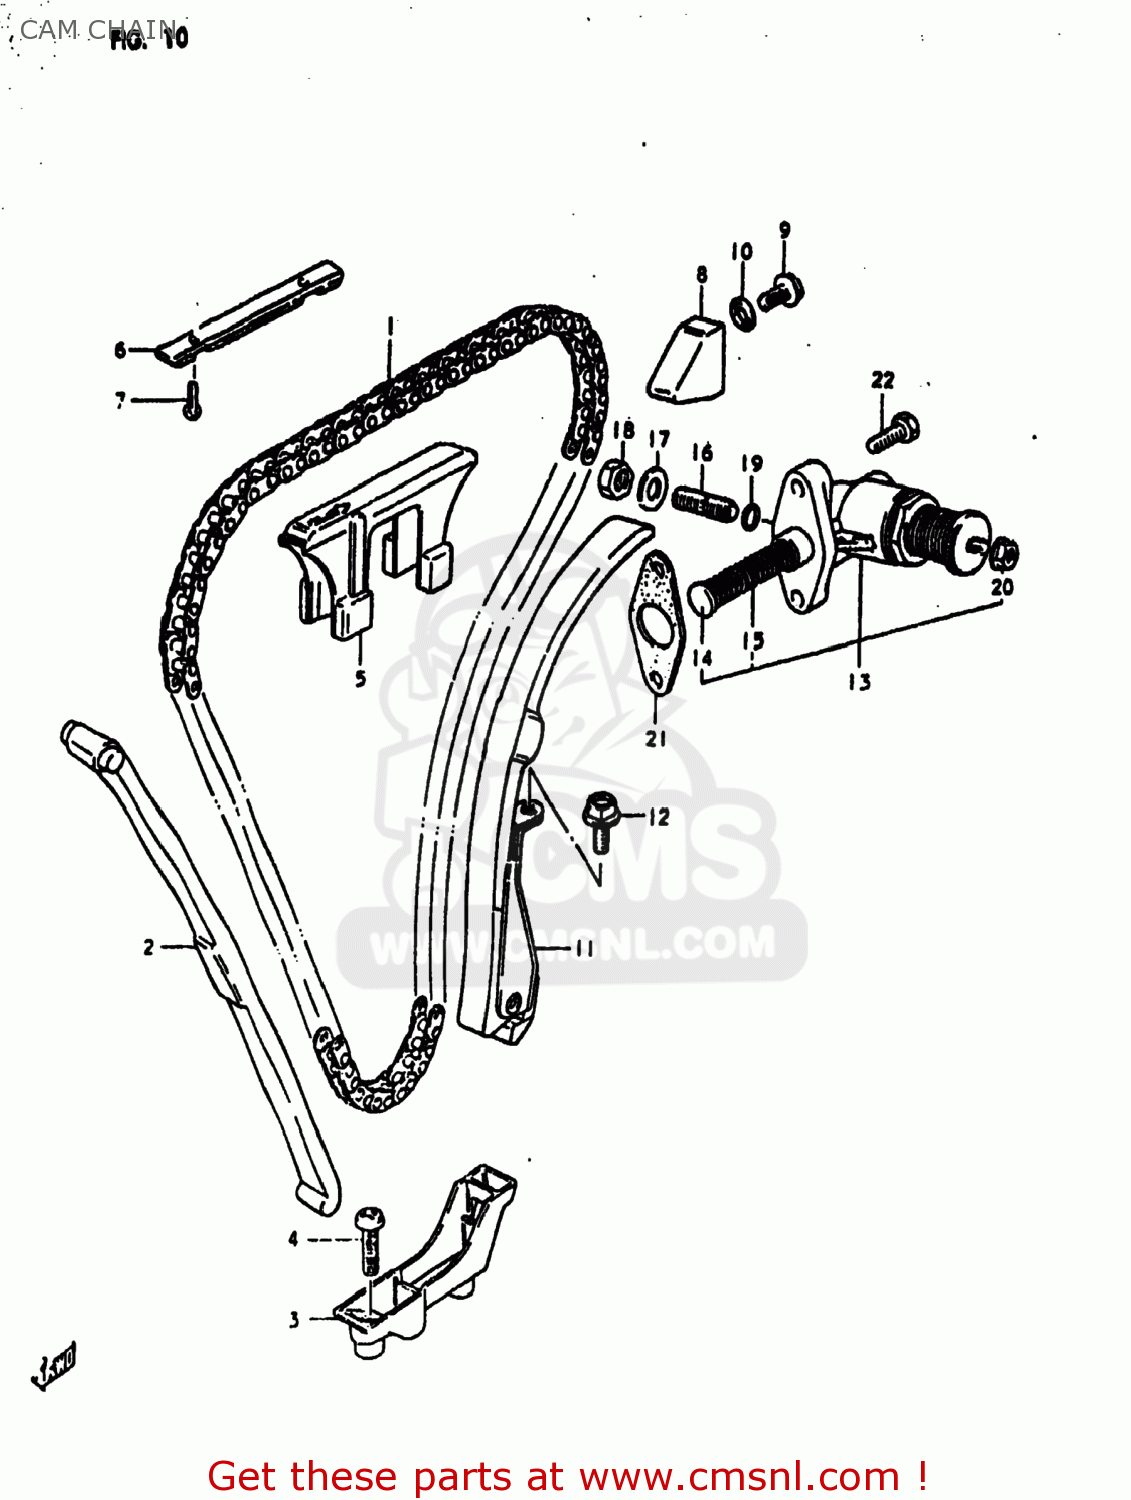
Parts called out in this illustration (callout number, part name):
1	CHAIN,CAMSHAFT DRIVE
2	GUIDE,CAM CHAIN NO.1
3	HOLDER,CAM CHAIN GUIDE
4	SCREW
5	GUIDE,CAM CHAIN NO.2
6	GUIDE,CAM CHAIN NO.3
7	SCREW
8	GUIDE,CAM CHAIN
9	BOLT
10	GASKET (NAS)
11	TENSIONER,CAM CHAIN
12	BOLT
13	ADJUSTER ASSEMBLY,TENSIONER
14	ROD,PUSH
15	SPRING
16	SCREW
17	WASHER
18	NUT
19	O-RING
20	NUT
21	GASKET,TENSIONER ADJUSTER (MCA)
22	SCREW (6X25)
